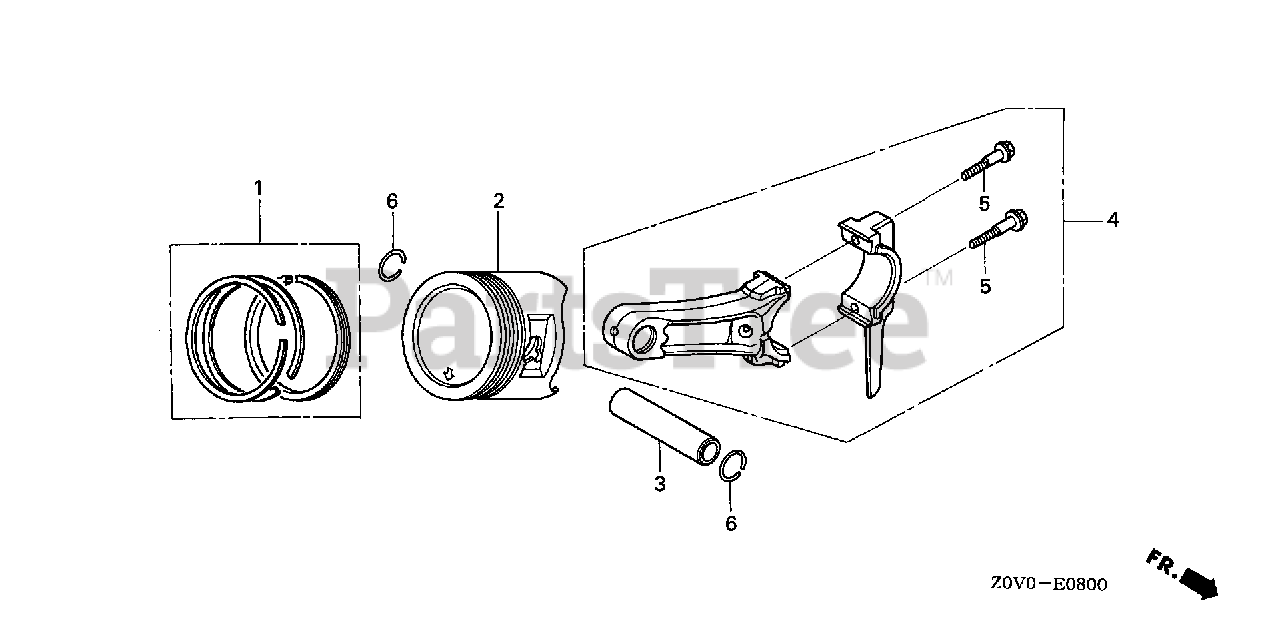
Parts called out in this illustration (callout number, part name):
1	RING SET, PISTON (STD) (TPR)
1	RING SET, PISTON (STD) (RIKEN)
1	RING SET, PISTON (0.25) Use from Engine SN 1314913.
1	RING SET, PISTON (0.25) (RIKEN)
1	RING SET, PISTON (0.50) (TPR)
1	RING SET, PISTON (0.50) (RIKEN)
1	RING SET, PISTON (0.75) Use from Engine SN 1314913.
1	RING SET, PISTON (0.75) (RIKEN)
2	PISTON (STD)
2	PISTON (0.25)
2	PISTON (0.50)
2	PISTON (0.75)
3	PIN, PISTON
4	ROD ASSY., CONNECTING
4	ROD ASSY., CONNECTING (UNDER SIZE) (NOT AVAILABLE)
5	BOLT, CONNECTING ROD
6	CLIP, PISTON PIN (18MM)
